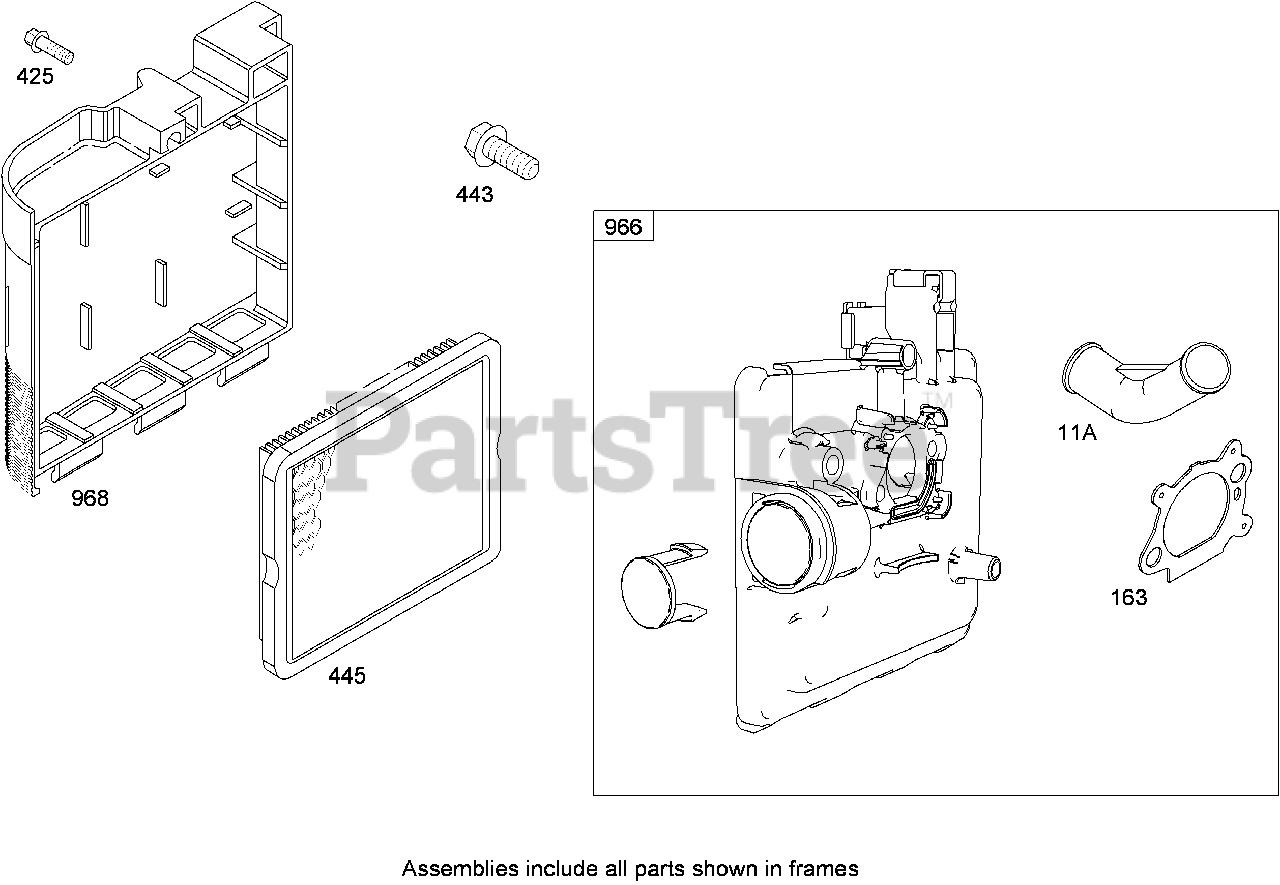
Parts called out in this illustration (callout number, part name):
11A	Tube-Breather (Air Cleaner Primer Base)
163	Gasket-Cleaner, Air
425	Screw (Air Cleaner Cover)
443	Screw (Air Cleaner Primer Base)
445	Filter-Cartridge, Air Cleaner
966	Base-Primer, Air Cleaner
968	Cover-Cleaner, Air
